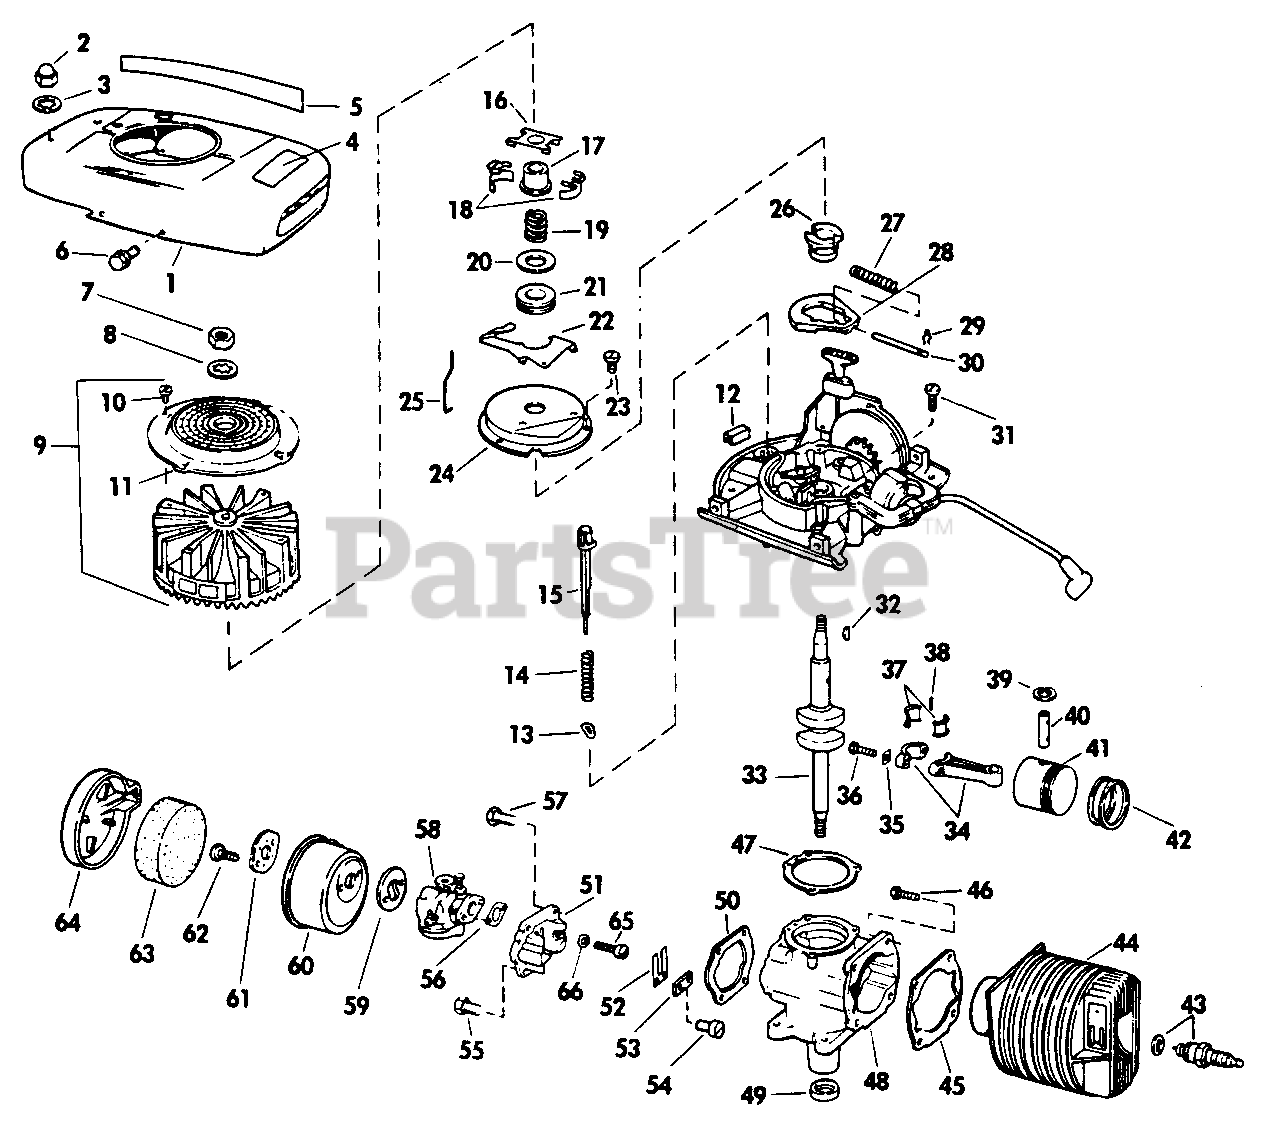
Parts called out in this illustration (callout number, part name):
1	Shroud, Tank & Shield Assy.
2	Acorn Nut
4	Decal-Instruction
5	Decal-LAWN-BOY
6	Screw-Shroud to Arm. Plate
7	Nut-Flywheel
8	Lockwasher-Flywheel
9	Flywheel and Screen Assembly
11	Screen
12	Pad-Rubber, Arm. Plate
13	Blade-Switch
14	Spring-Shut-Off Switch
15	Bar-Shut-Off & Primer
16	Yoke-Governor
17	Collar-Governor
18	Weight-Governor
19	Spring-Governor
20	Thrust Washer
21	Collar-Thrust
22	Lever-Governor
23	Screw-Attaching Dust Cover
24	Dust Cover
25	Rod-Governor
26	Cam-Spark Advance
27	Spring-Spark Advance
28	Flywheel-Spark Advance
29	Retainer-Spring
30	Pin-Spark Advance
31	Screw-Arm. Plate to Crankcase
32	Key-Crankshaft
33	Crankshaft
34	Connecting Rod Assy.
35	Lockplate
37	Liners-Conn. Rod
38	Needle Bearing Set
39	Retaining Ring-Wrist Pin
40	Wrist Pin
42	Ring Set (2 rings)
43	Spark Plug & Gasket Champion CJ-14, .025" Gap
44	Cylinder & Sleeve Assy.
45	Gasket-Cyl. to Crankcase
46	Screw-Mach., Cyl. to Crankcase
47	Gasket-Crkc. to Arm. Pl.-.005"
47	Gasket-Crkc. to Arm. Pl.-.010"
48	Crankcase Assy.
49	Oil Seal
50	Gasket-Reed Plate
51	Reed Plate Assembly
53	Plate-Back-Up
54	Screw-Machine
55	Screw-H.H., Reed Pl. to Crkc.
56	Gasket-Carburetor
57	Screw-H.H., Reed Pl. to Crkc.
58	Carburetor Assy.
60	Chamber
61	Washer-Back-Up
63	Element
64	Cap
65	Screw-Reg. Plate to Carb.
